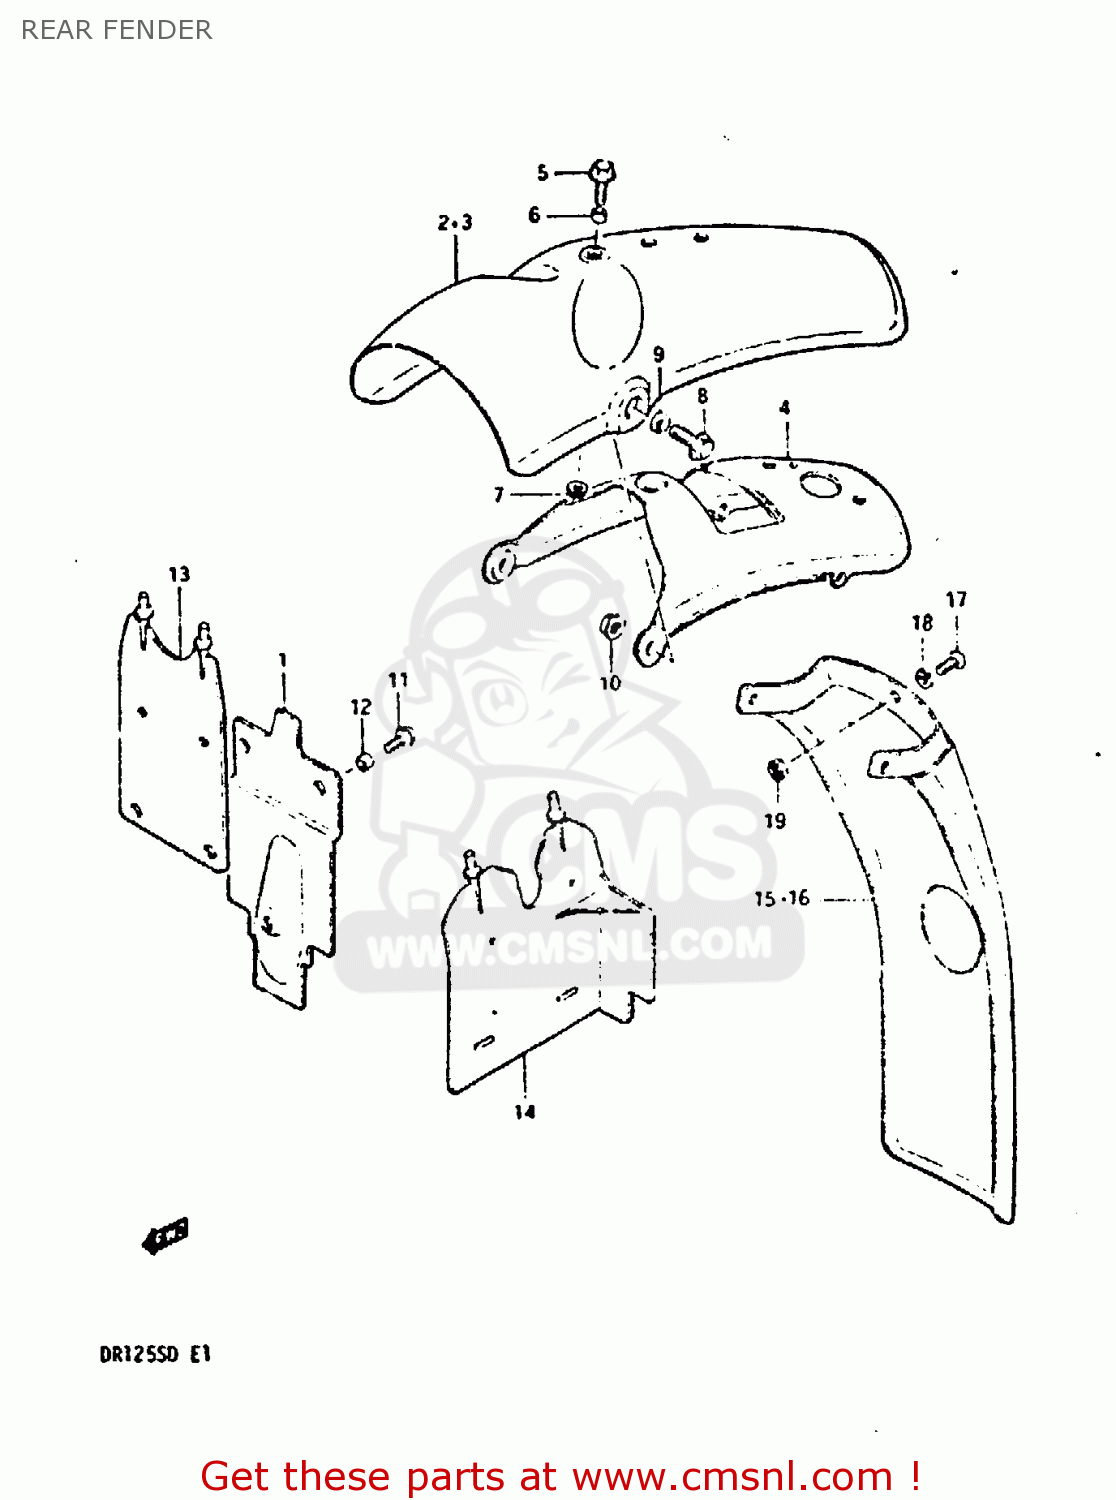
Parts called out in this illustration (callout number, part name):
1	REAR FENDER,FRONT
2	FENDER, REAR (BLUE)
4	REINFORCEMENT,REAR FENDER
5	BOLT,REAR
6	SPACER
7	NUT
8	BOLT
9	SPACER(8.2X14X4.5)
10	NUT
11	SCREW, FRONT
12	SPACER
13	MUD GUARD,REAR FENDER
14	MUD GUARD
